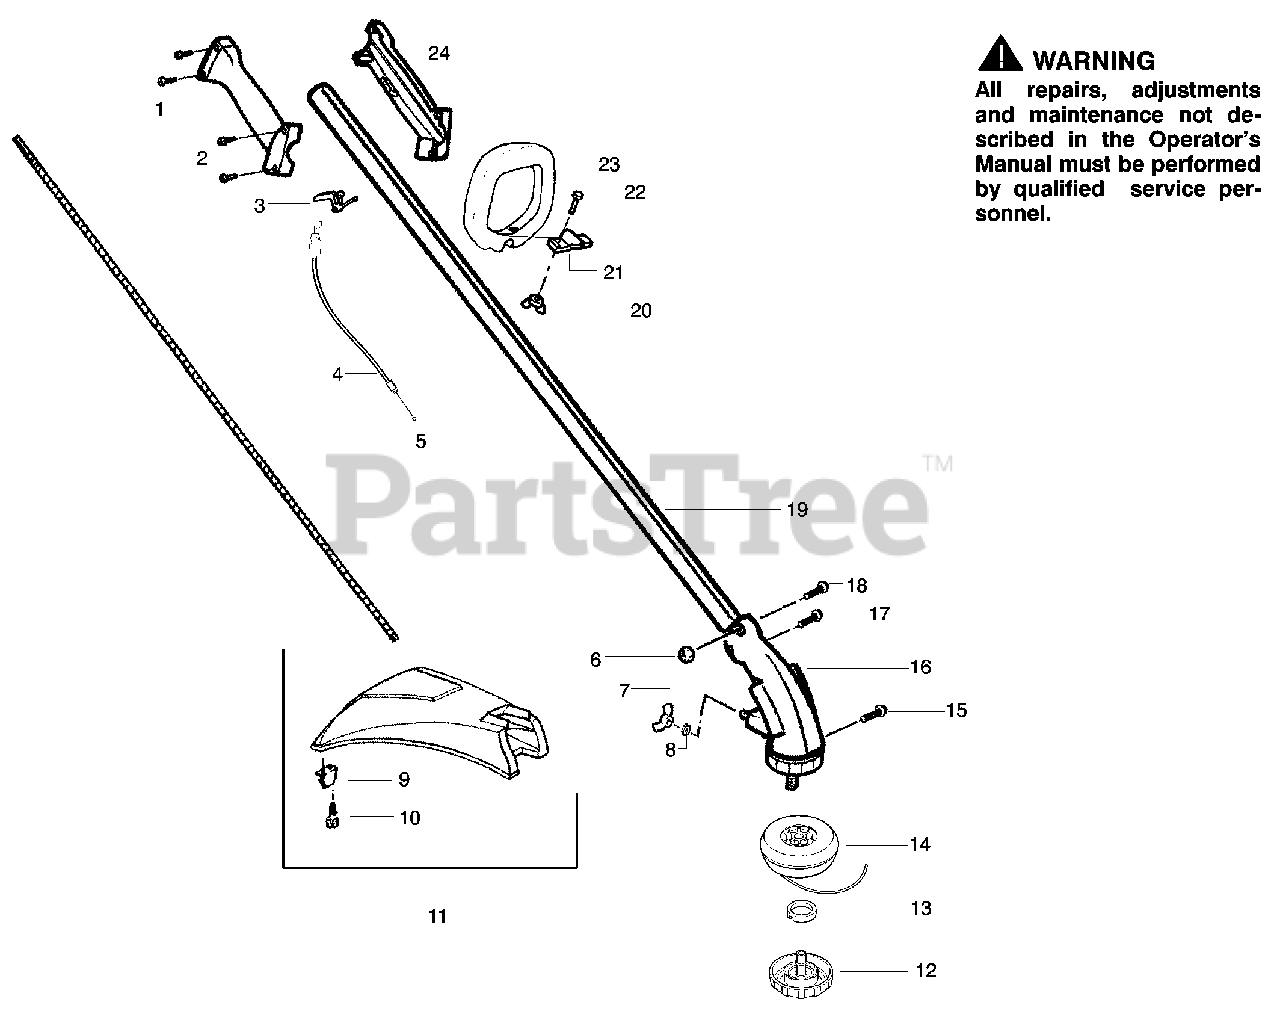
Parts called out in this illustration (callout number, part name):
1	Hsg.-Throttle (Right)
2	Screw-Throttle Hsg.
4	Kit-Throttle Cable
5	Flex-Shaft 52"
6	Locknut-Gear Box
7	Wingnut-Gear Box
9	Line Limiter
10	Screw-Line Limiter
11	Kit-Shield Ass'y.
12	Assy-Cap
13	Guide-Line
14	Accy.- Wound Hub
16	Assy-Gear Box
19	Assy-Drive Shaft Hsg.
20	Wingnut-Handle
21	Clamp-Handle
22	Bolt-Handle
23	Handle-Assist
24	Hsg.-Throttle (Left)
